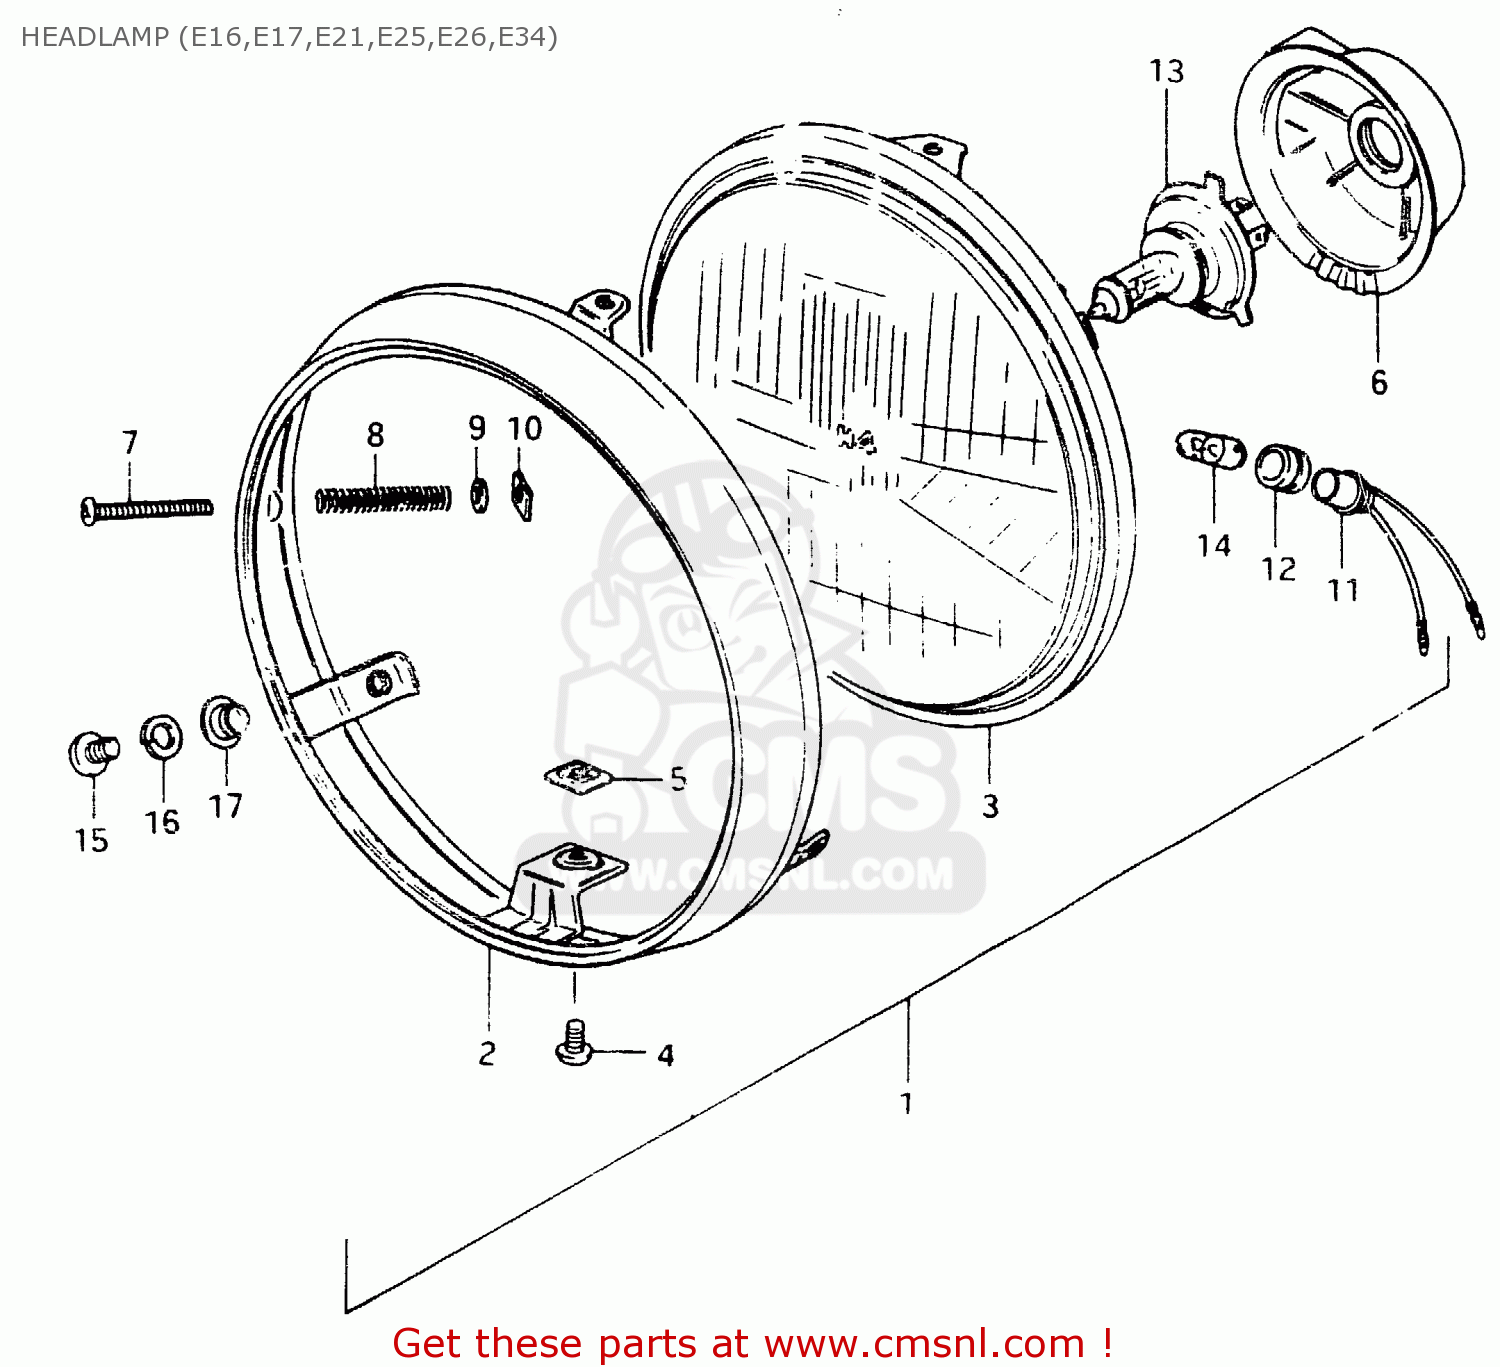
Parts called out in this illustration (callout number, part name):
1	HEADLAMP ASSY
2	RIM
3	LAMP UNIT
4	SCREW
5	NUT,ADJUSTING
6	COVER,SOCKET
7	SCREW
8	SPRING
9	WASHER
10	NUT,HEADLAMP ADJUSTER
11	SOCKET
12	JOINT,RUBBER
13	BULB(12V60/55W,H4)
14	BULB(12V4W)
15	SCREW
16	WASHER,LOCK
17	WASHER
